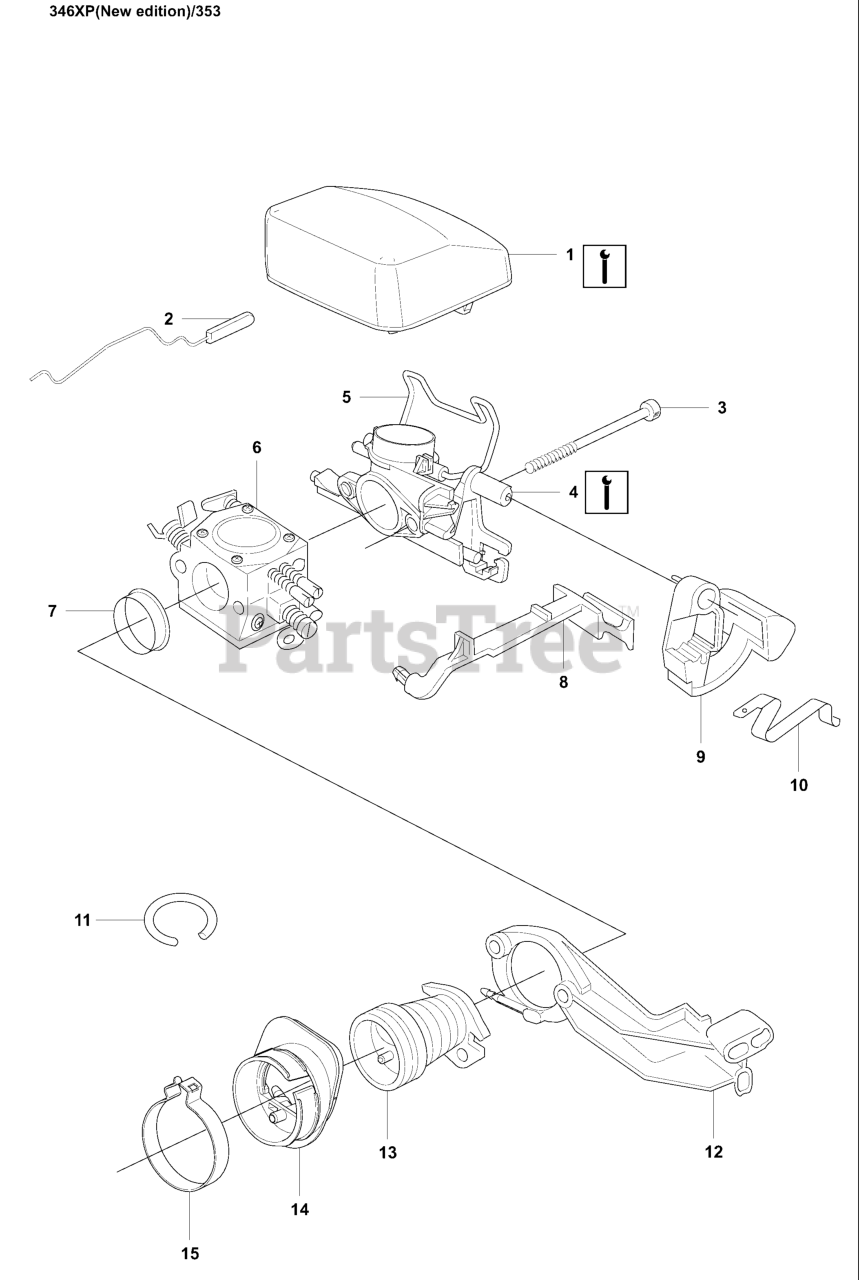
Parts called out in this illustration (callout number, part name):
1	AIR FILTER - NYLON (B)
1	AIR FILTER - NYLON (Y)
1	AIR FILTER - FELT
2	THROTTLE ROD
4	INLET ELBOW
5	FILTER CLAMP
6	CARBURETOR
8	CHOKE CONTROL
11	HOSE, IMPULSE
13	BELLOWS
15	CLAMP, INTAKE
